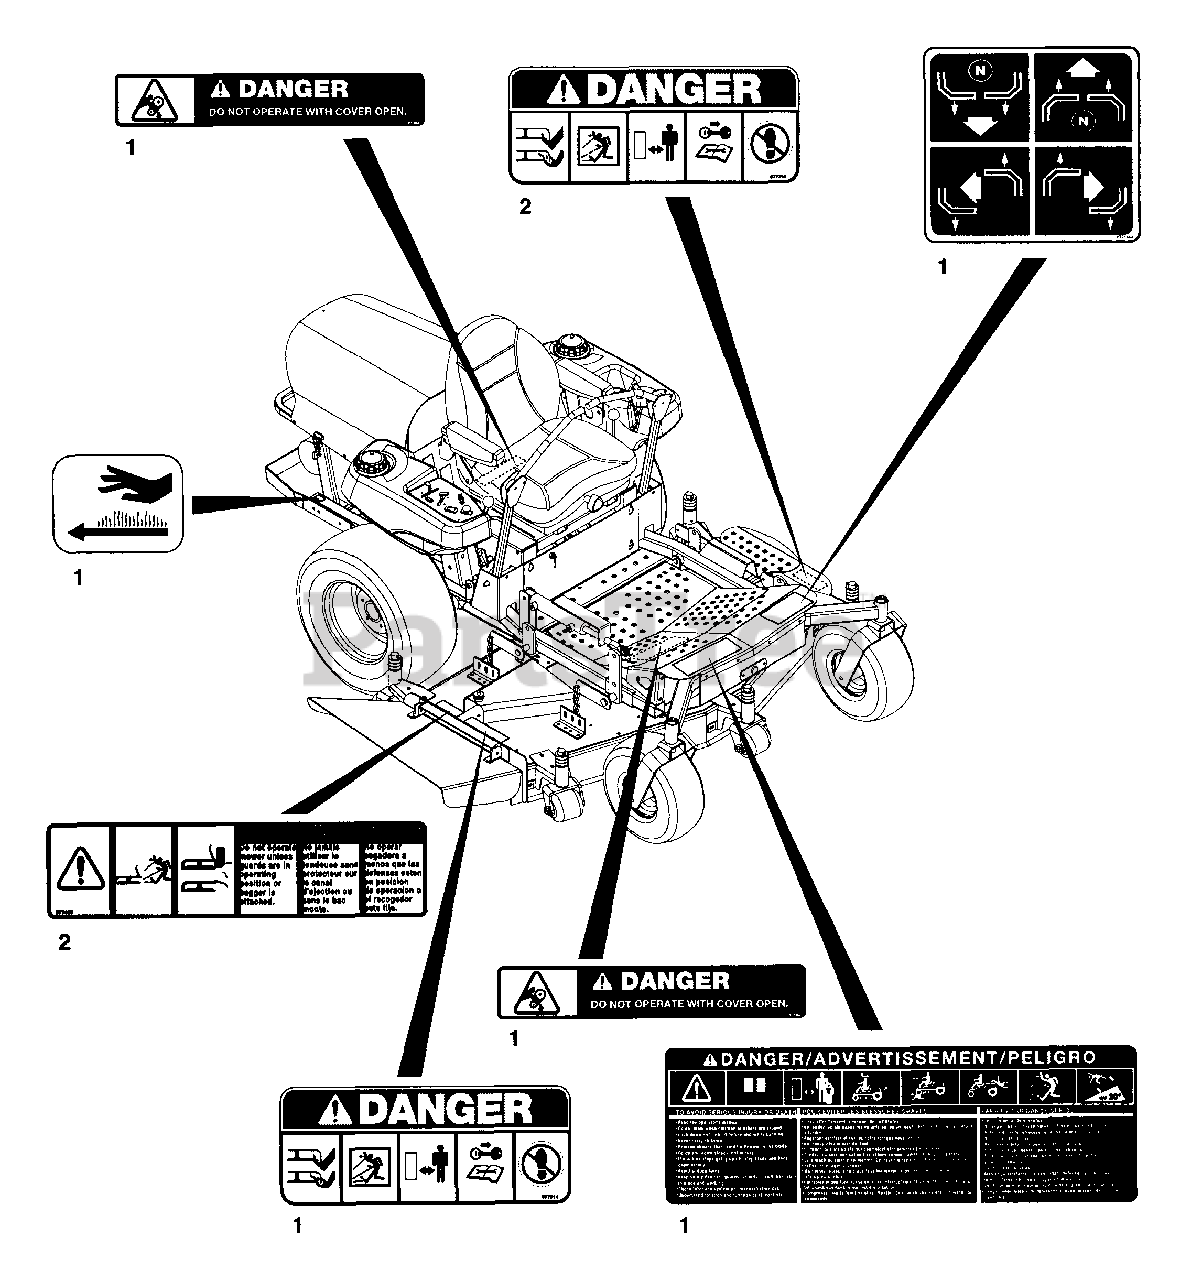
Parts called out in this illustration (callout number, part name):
1	Decal Set PM260Z
2	Decal Set Mower Decks
3	Decal, GRAVELY Belt Diagram
4	Decal Set GRAVELY Logo
